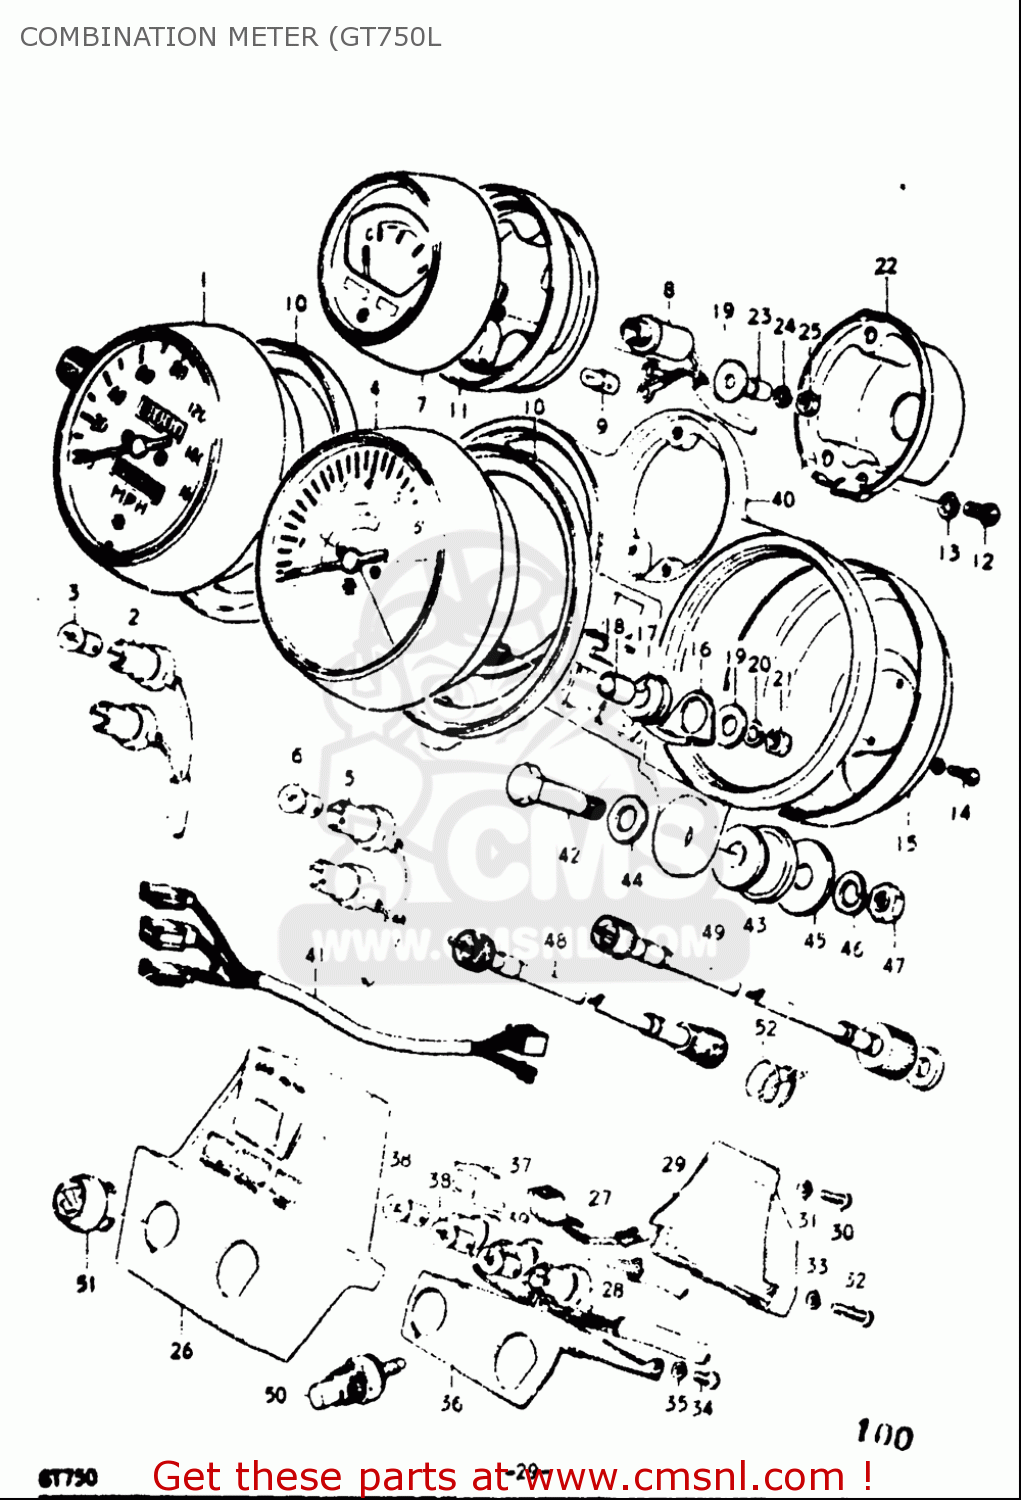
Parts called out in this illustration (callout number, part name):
3	BULB(12V3.4W,STANLEY,A72A)
6	BULB(12V3.4W,STANLEY,A72A)
7	THERMOMETER ASSEMBLY
9	BULB(12V2W,STANLEY,A1272J)
10	CUSHION,SPEEDOMETER
12	SCREW
13	WASHER,LOCK
14	SCREW
15	PLATE,UNDER
18	SPACER,METER
19	WASHER(5.5X16X1.2)
20	WASHER,LOCK
21	NUT
24	WASHER,LOCK
25	NUT
26	CASE,PILOT BULB
30	SCREW
31	WASHER,LOCK
32	SCREW
33	WASHER,LOCK
34	SCREW 4X6
35	WASHER,LOCK
36	BRACKET (BB)
38	BULB(12V3.4W,STANLEY,A72A)
39	BULB(12V1.7W,A71A)
42	BOLT(8X39.2)
43	CUSHION,METER BRACKET
44	WASHER
45	WASHER(8.5X28X1.6)
46	WASHER,LOCK
47	NUT
48	CABLE ASSY,SPEEDOMETER
49	CABLE ASSY,TACHOMETER
50	GAUGE ASSY,WATER TEMP
51	CAP,SPEED WARNER LAMP HOLE
